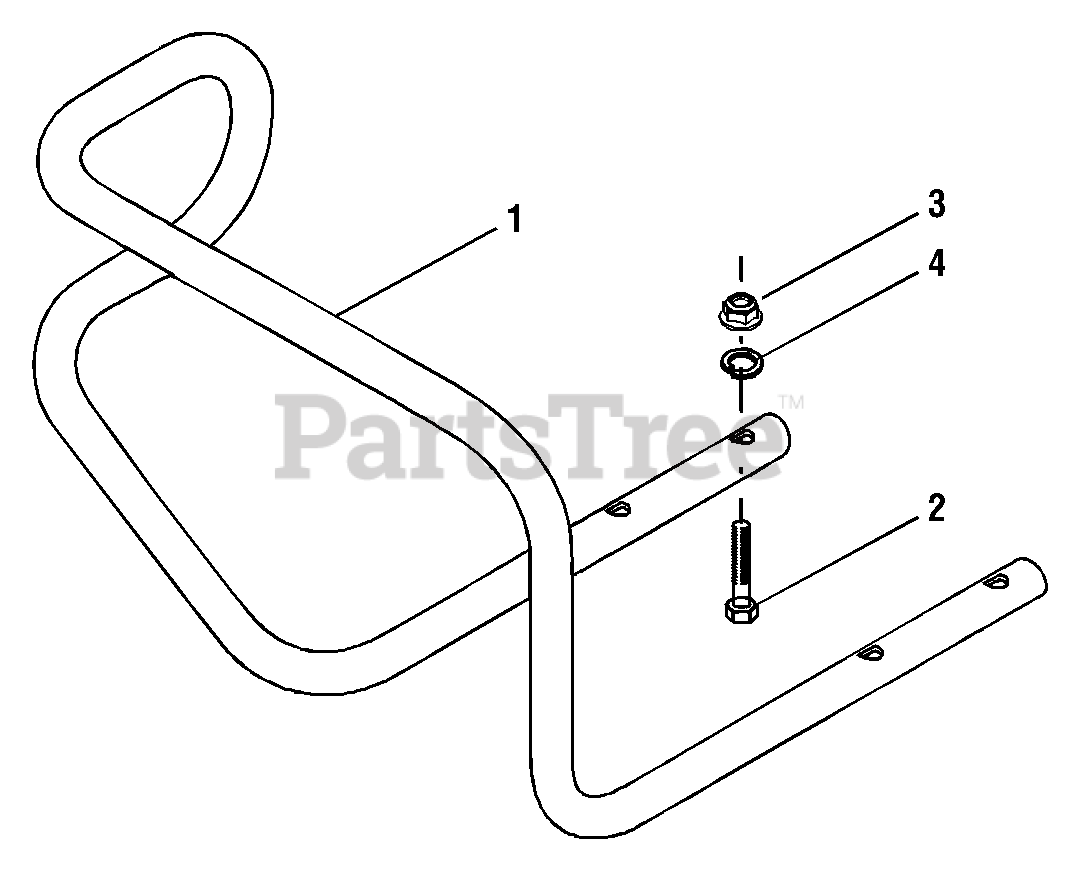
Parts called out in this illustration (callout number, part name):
2	Hex Screw, 5/16-18 x 2-1/4
3	Nut, Flange Lock, 5/16-18
4	Speed Nut
